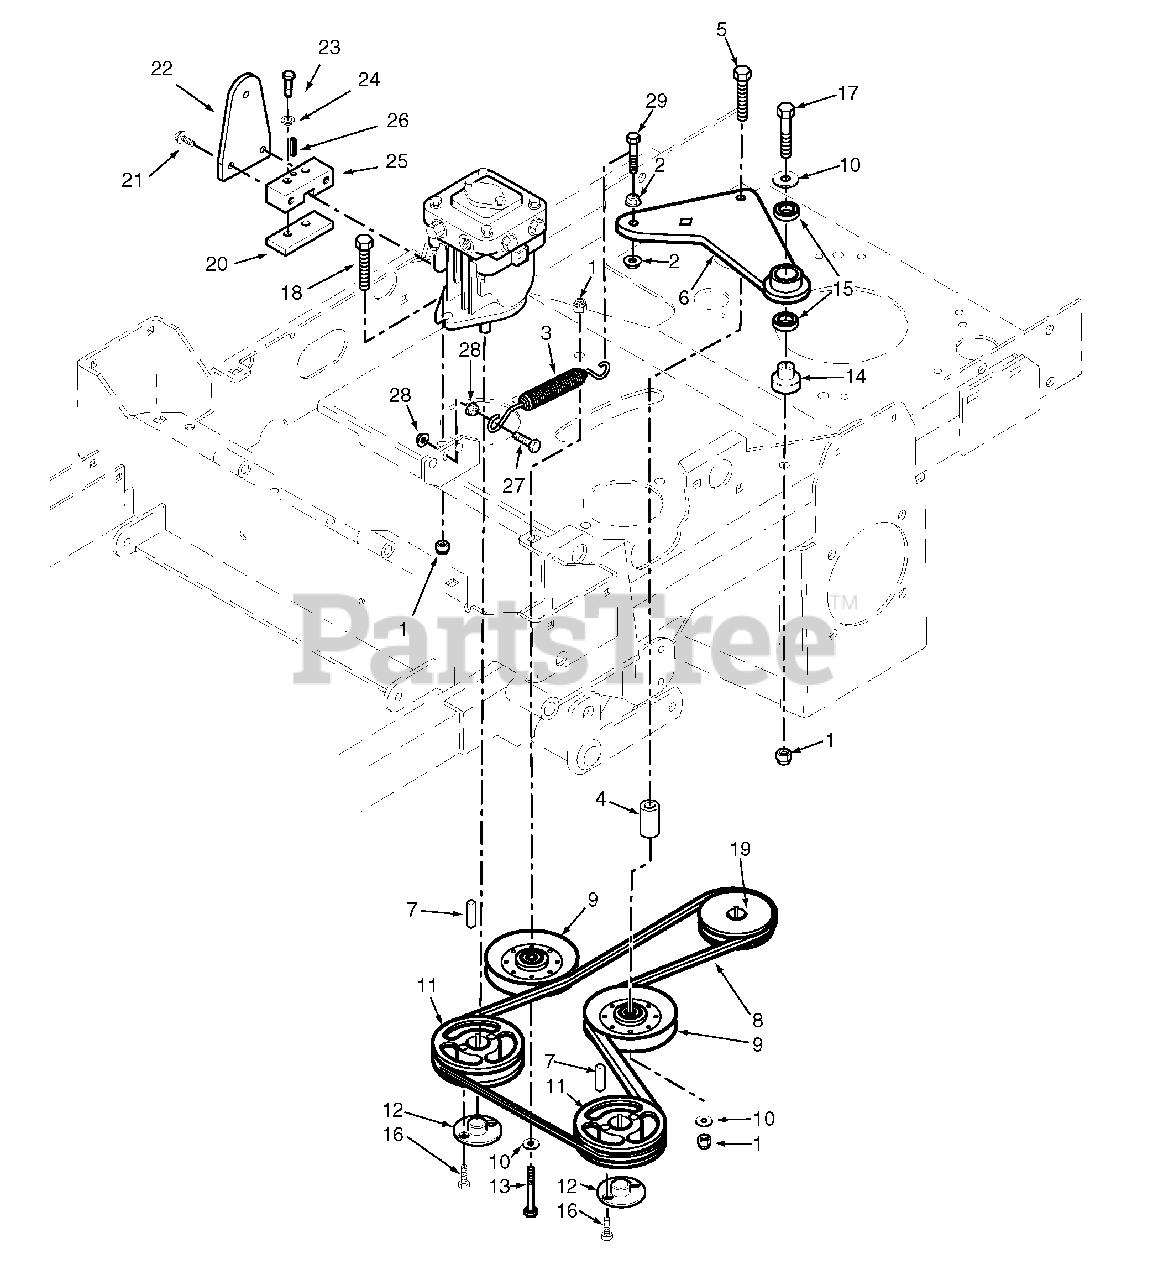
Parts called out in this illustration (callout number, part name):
1	Nut, Elastic Stop 3/8-16
2	Nut, Serrated Flange 3/8-16
3	Spring, Pump Idler
4	Spacer
5	Bolt, Hex Head 3/8-16 x 2-3/4"
6	Idler Arm Assy., Pump Drive
7	Key, 5 x 5 x 25mm
8	Belt, Transmission
9	Pulley, 3" Dia. Idler
10	Flatwasher, 3/8-.391 x .938 x .105
11	Pulley, 5.45 OD Taper Bore
12	Hub, Tapered, 15mm Bore
13	Bolt, 3/8-16 x 2"
14	Pivot, Idler
15	Bearing
16	Bolt, Hex Head 1/4-20 x 1"
17	Bolt, Hex Head 3/8-16 x 2-1/2"
18	Bolt, Hex Head 3/8-16 x 1-1/2"
19	Pulley, 4.45 Dia. - 1" Bore
20	Clamp Plate
21	Hex Head Capscrew, 1/4-20 x 3/4"
22	Control Lever, Pump
23	Hex Head Capscrew, 1/4-20 x 3/4"
24	Lockwasher, 1/4"
25	Block, Pump Control
26	Roll Pin
27	Bolt, Hex Head 3/8-16 x 1-1/2"
28	Nut, Serr. Flange 3/8-16
29	Bolt, Hex Head 3/8-16 x 1-1/2"
